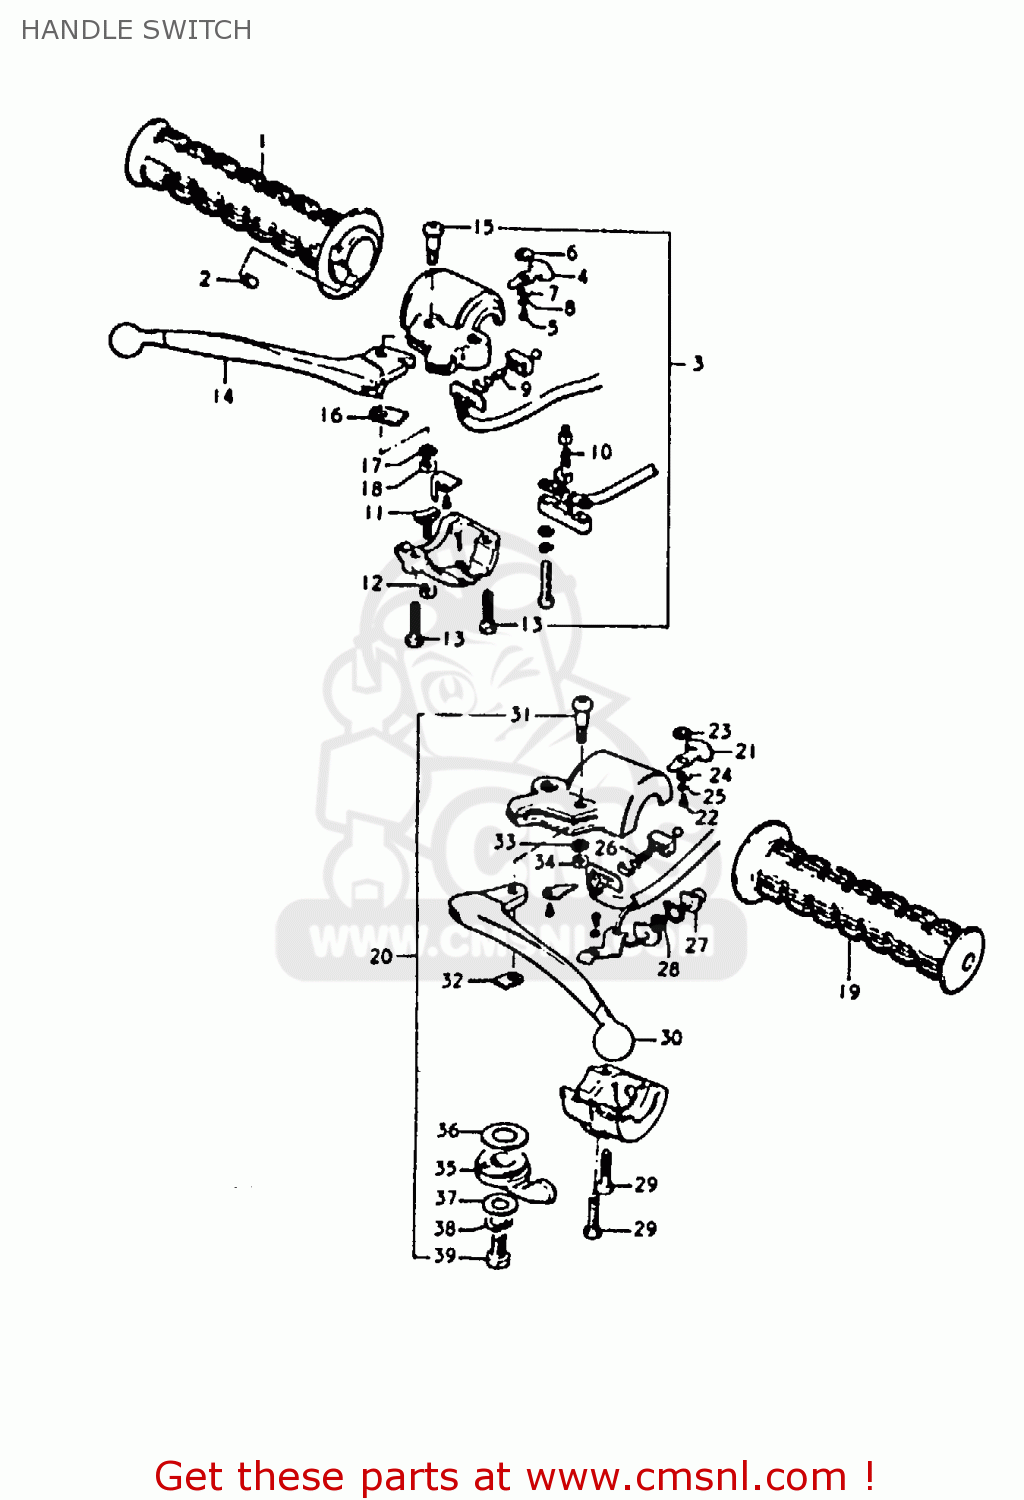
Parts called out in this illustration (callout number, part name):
1	GRIP,THROTTLE
2	PIECE,THROTTLE END
3	LEVER/SWITCH ASSEMBLY,BRAKE
4	KNOB,DIMMER SWITCH
5	SCREW
6	WASHER,DIM SWITCH KNOB
7	WASHER
8	LOCK WASHER
9	SPRING,TURN SIGNAL SWITCH CONTACT
11	ADJUSTER,GRIP
12	NUT
13	SCREW
14	LEVER,BRAKE
15	BOLT,LEVER
16	SPACER,LEVER
17	LOCK WASHER
18	NUT
19	GRIP
20	LEVER ASSEMBLY
21	KNOB,DIMMER SWITCH
22	SCREW
23	WASHER,DIM SWITCH KNOB
24	WASHER
25	LOCK WASHER
26	SPRING,TURN SIGNAL SWITCH CONTACT
27	BUTTON
28	SPRING
29	SCREW
30	LEVER,CLUTCH
31	BOLT,LEVER
32	SPACER,LEVER
33	LOCK WASHER
34	NUT
35	LEVER,STARTER
36	WASHER,ADJUSTER
37	WASHER,STARTER LEVER
38	LOCK WASHER
39	BOLT
